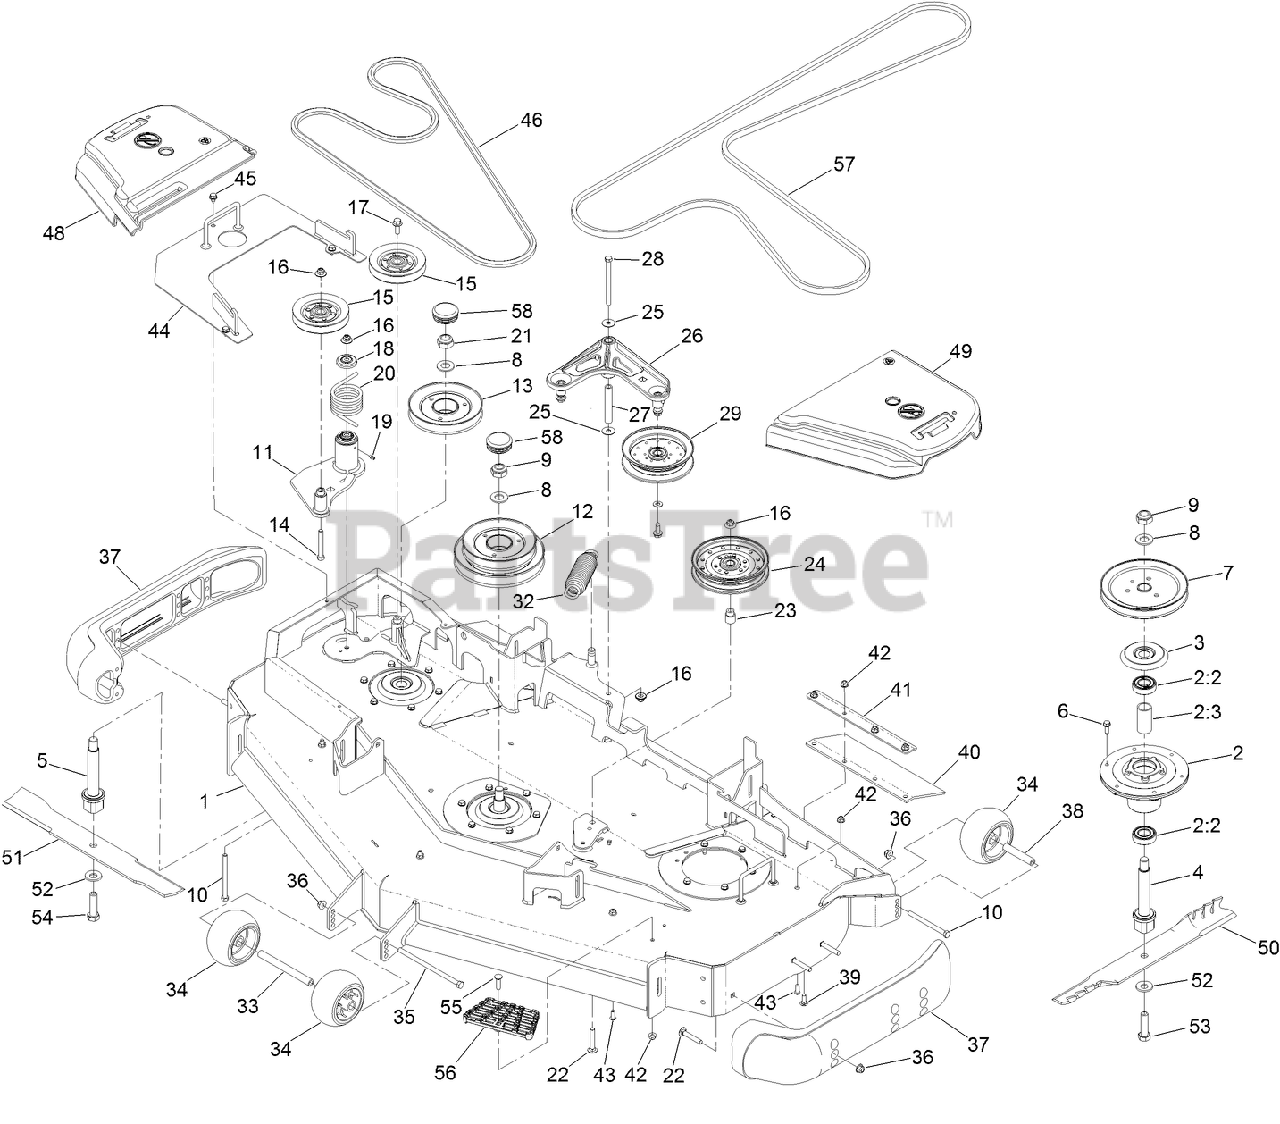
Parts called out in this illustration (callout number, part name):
1	DECK DECAL ASM
2	SPINDLE ASM
2:2	BEARING-BALL
2:3	SPACER-BEARING
3	SHIELD-BEARING
4	SHAFT-SPINDLE
5	SHAFT-SPINDLE, LH THREAD
6	SCREW-HWHTF
7	PULLEY B SECTION
8	WASHER
9	NUT-LOCK, NI
10	SCREW-HH
11	IDLER ASM
12	SHEAVE-DOUBLE
13	SHEAVE
14	SCREW-HH
15	SHEAVE
16	NUT-FLANGE, NI
17	SCREW-HHF
18	GUARD-TOP
19	FITTING-GREASE
20	SPRING-TORSION
21	NUT-LOCK,NI LEFT HAND THREAD
22	SCREW-CARR
23	Bushing, Idler
24	PULLEY-IDLER, FLAT
25	WASHER
26	IDLER ARM ASM
27	BUSHING
28	SCREW-HH
29	IDLER-PULLEY, FLANGED
32	SPRING-EXTENSION
33	SPACER-WHEEL
34	ROLLER-SCALP, ANTI
35	SCREW-HH
36	NUT-HF, NI
37	SKID-BUMPER, DECK
38	TUBE-SPANNER
39	SCREW-CARR
40	GUARD-TIRE
41	SUPPORT-OUTER FLAP
42	NUT-HF, NI
43	SCREW-HSBH
44	ASM-REV DRIVE 60RD
45	SCREW
48	COVER-BELT, RH
49	COVER-BELT, LH
50	BLADE-ROTARY, ATOMIC 20.5
51	BLADE-ROTARY, CR 20.5 LOW FLOW
52	WASHER-BELLEVILLE
53	SCREW-BLADE
54	SCREW-BLADE, LH
55	SCREW-CARR
56	STEP-DECK
57	BELT-V
58	CAPLUG-ROUND
